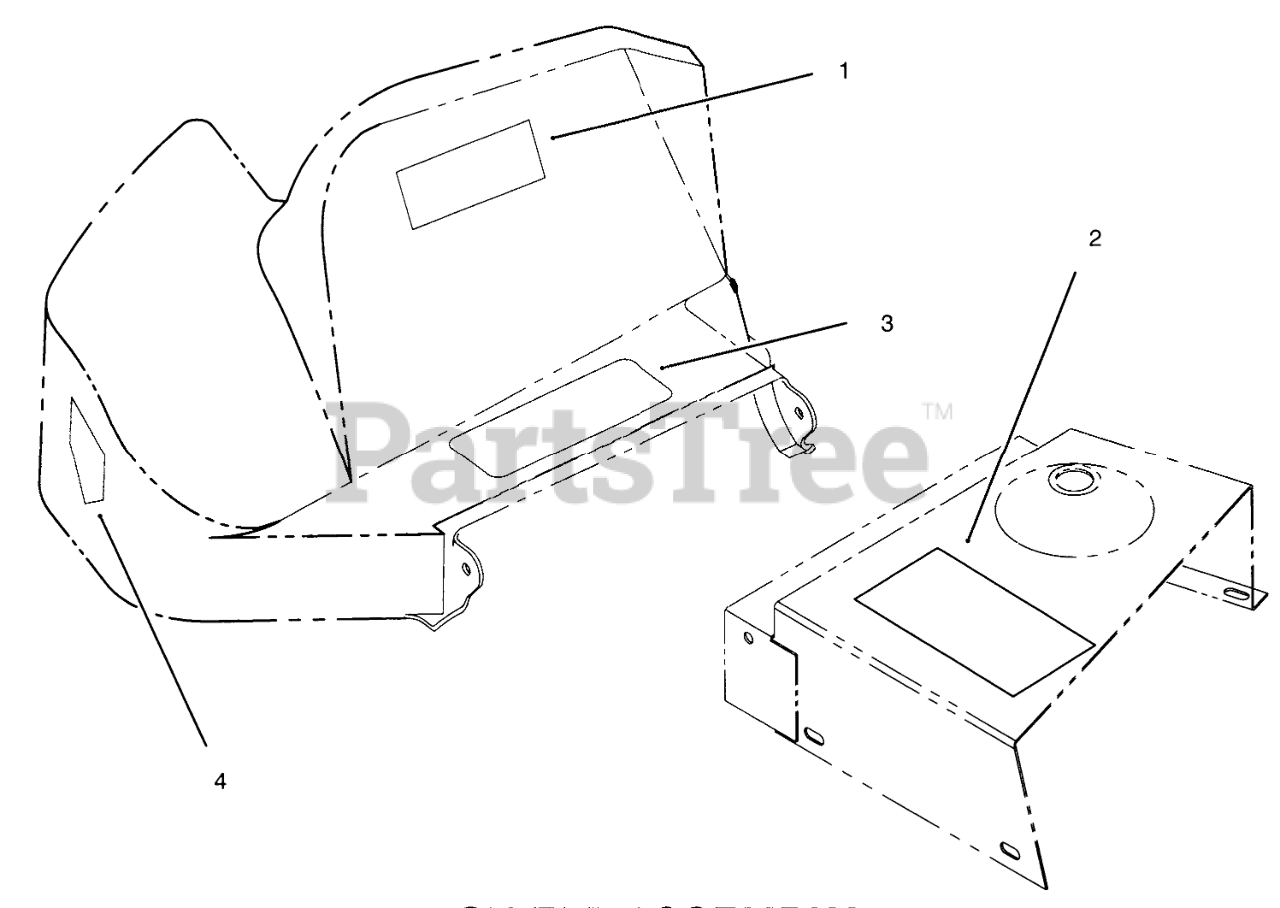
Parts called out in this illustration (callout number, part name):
1	DECAL - WARNING
2	DECAL-DANGER
3	DECAL-DANGER
4	DECAL-DANGER
